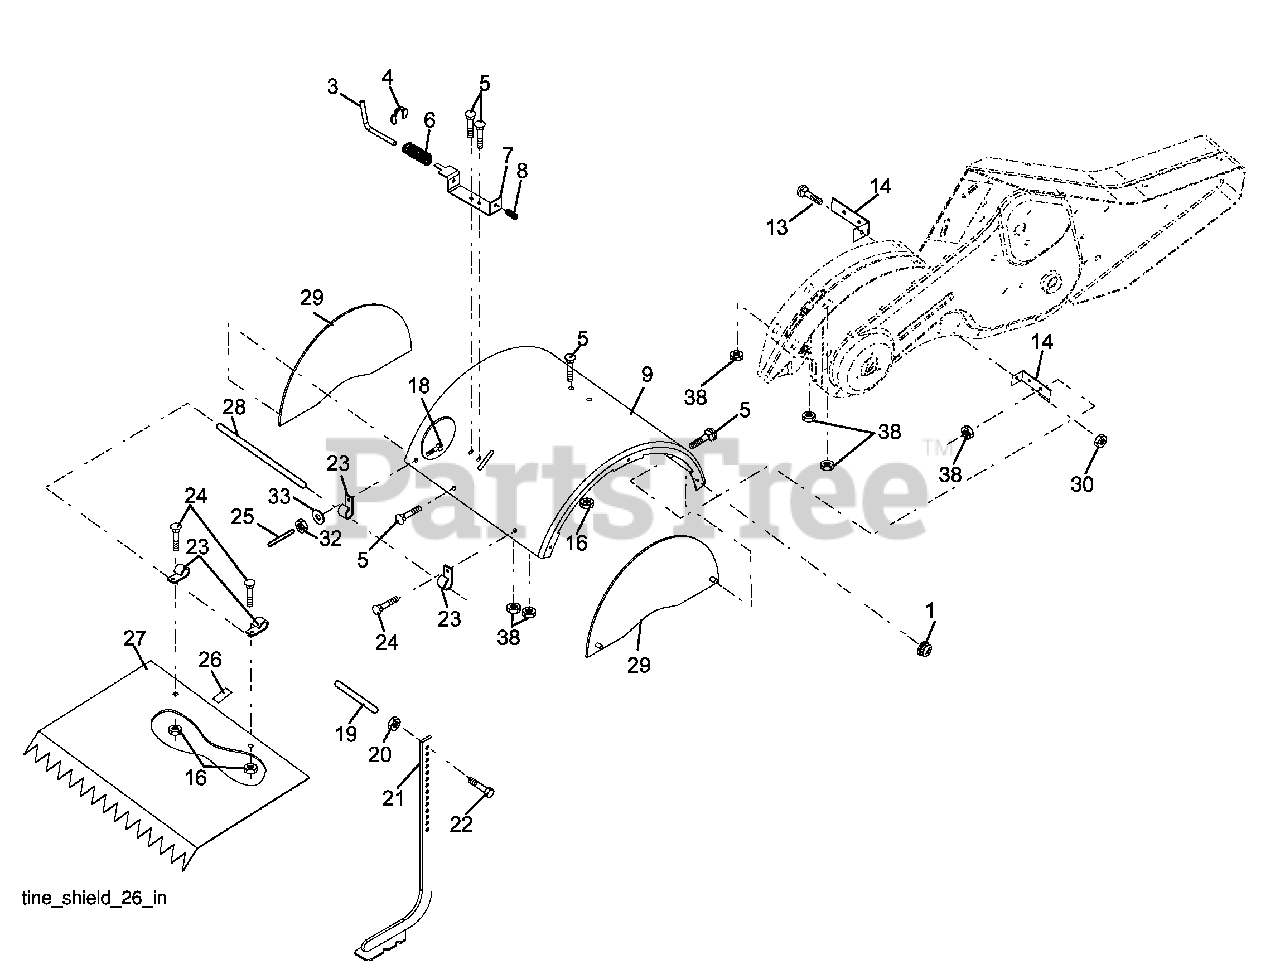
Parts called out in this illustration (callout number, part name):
1	Nut, Lock Hex Flange 5/16-18
3	Pin, Stake, Depth
4	Ring, Klip
5	Bolt, Rdhd Sqnk 5/16-18 x 3/4
7	Bracket, Latch
8	Spring, Depth Stake
9	Shield, Tine
13	Bolt, Carriage 5/16-18 x 1-1/4
14	Bracket, Shield Tine
16	Nut, Hex Flange 1/4-20 unc
18	Bolt, Carriage 1/4-20 x 1-1/4 Gr.
20	Nut, Hex 3/8-16
21	Stake, Depth
22	Bolt, Hex 3/8-16 x 2
24	Bolt, Carriage 1/4-20 x 1/2 Gr. 5
25	Cap, Vinyl
26	Pad, Idler
27	Shield, Leveling
28	Pin, Hinge
29	Shield, Side
30	Nut Lock Hex Flange
32	Nut Fin Hex 1/4-20 unc
33	Washer Lock Hvy Helical 1/4
38	Nut, Keps Hex 5/16-18 unc
